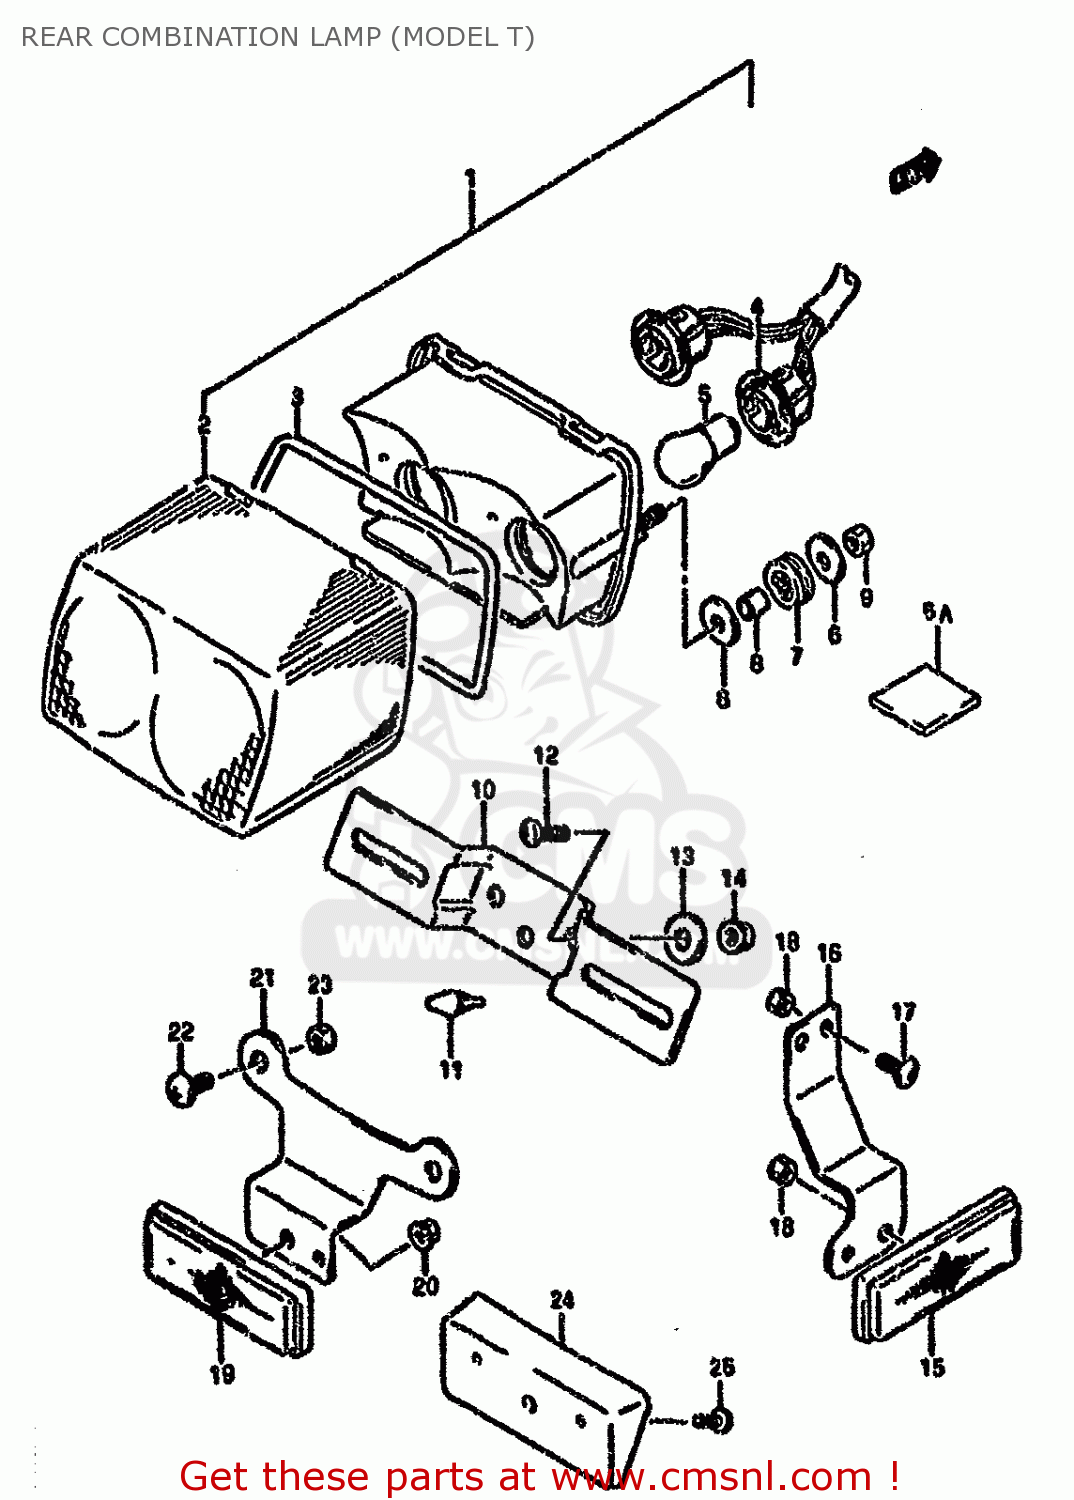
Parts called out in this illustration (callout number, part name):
1	LAMP ASSY,RR C
2	LENS
3	GASKET (NAS)
4	SOCKET
5	BULB(12V21/5W)
5A	CUSHION,REAR LENS
6	WASHER(6.5X20X1.2)
7	CUSHION
8	SPACER
9	NUT 6MM
10	BRACKET,LICENSE PLATE
11	CUSHION
12	SCREW
13	WASHER(6.5X20X1.2)
14	NUT 6MM
15	REFLEX REFLECTOR,FR SIDE
16	BRACKET,RR SIDE REFLECTOR
17	SCREW 5X12
18	NUT
19	REFLECTOR ASSY,RR
20	NUT
21	BRACKET,RR RR
22	SCREW 6X12
23	NUT 6MM
24	NUT
25	SCREW
26	SPACER,RR RR
27	SCREW
28	WASHER
